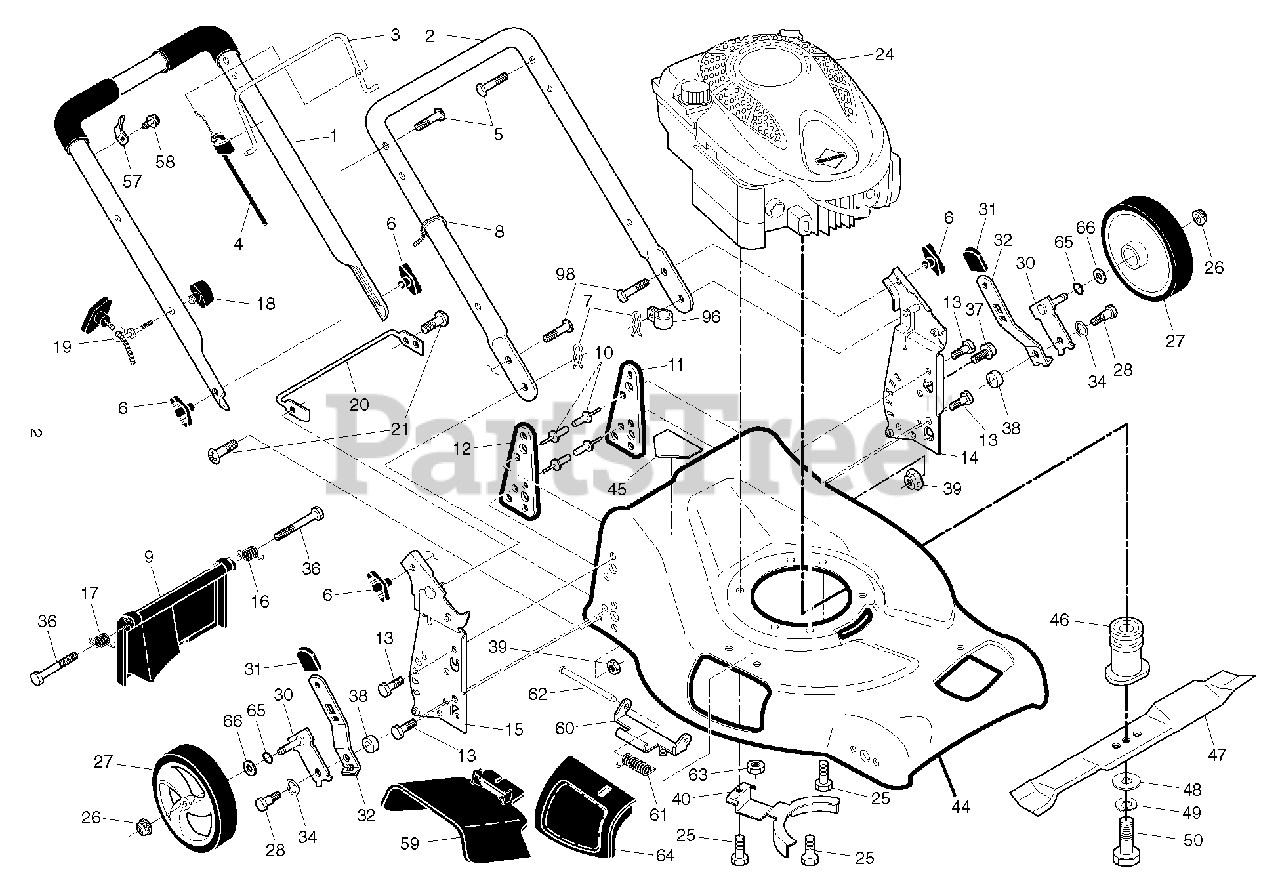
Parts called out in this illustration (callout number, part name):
1	HANDLE.ASM.UP.BS.AW2.GRIP.479
2	HANDLE.LOWER.D-STRAIT.BLACK
4	CABLE.ASM.ZONE.CONTROL
5	BOLT, HANDLE 5/16-18X1.75
6	KNOB, DEFLECTOR
7	HAIRPIN COTTER
8	TIE GUIDE
9	REAR DOOR ASSEMBLY
10	RIVET BLIND
11	SUPPORT BRACKET LH
12	BRACKET.SUPRT.RH.21.FWGD
13	SCREW 14-20 X 5/8
14	Handle Bracket Assembly, LH 21 Fwgd
15	BRACKET.ASM.HANDLE.RT.21.FWGD
16	SPRING.REAR.DOOR.EZ.21.LT
17	SPRING.REAR.DOOR.EZ.21.RT
18	T-Knob, New Rope Guide
19	Rope Guide, Blk Zinc Chrom
21	SCREW
25	BOLT 3/8-16X1-1/8
26	NUT.HEX.FLANGE.3/8-16.LOCKNUT
28	SHOULDER BOLT 5/16-18
30	Handle Bracket Assembly, LH 21 Fwgd
31	SELECTOR KNOB
32	SPRING.SELECTOR.21RD.HTTRT.BZP
34	WASHER FLAT
37	SCREW 14-20 X 5/8
38	SPACER.HEIGHT.ADJUSTER
39	NUT.FLANGE.5/16
40	BRACKET.ENG/BELTKEEPER
45	DECAL.INTERNATIONL.CUTFINGER
47	BLADE.21.PUSH
48	WASHER,HARDEN
49	LOCKWASHER
50	SCREW, HEX HD 3/8-24 X 1-3/8
57	BRACKET.UPSTOP.RT
59	DISCHARGE DEFLECTOR
60	HINGE BRACKET ASSEMBLY
61	SPRING.TORSION
62	ROD.HINGE.21
63	LOCKNUT
64	DOOR.MULCH.21.REAR
65	O-RING..070X.487.NEOPRENE
66	WASHER PM
96	CLIP.CABLE.BLK
98	Carriage Bolt, 5/16-18 X 5/8
